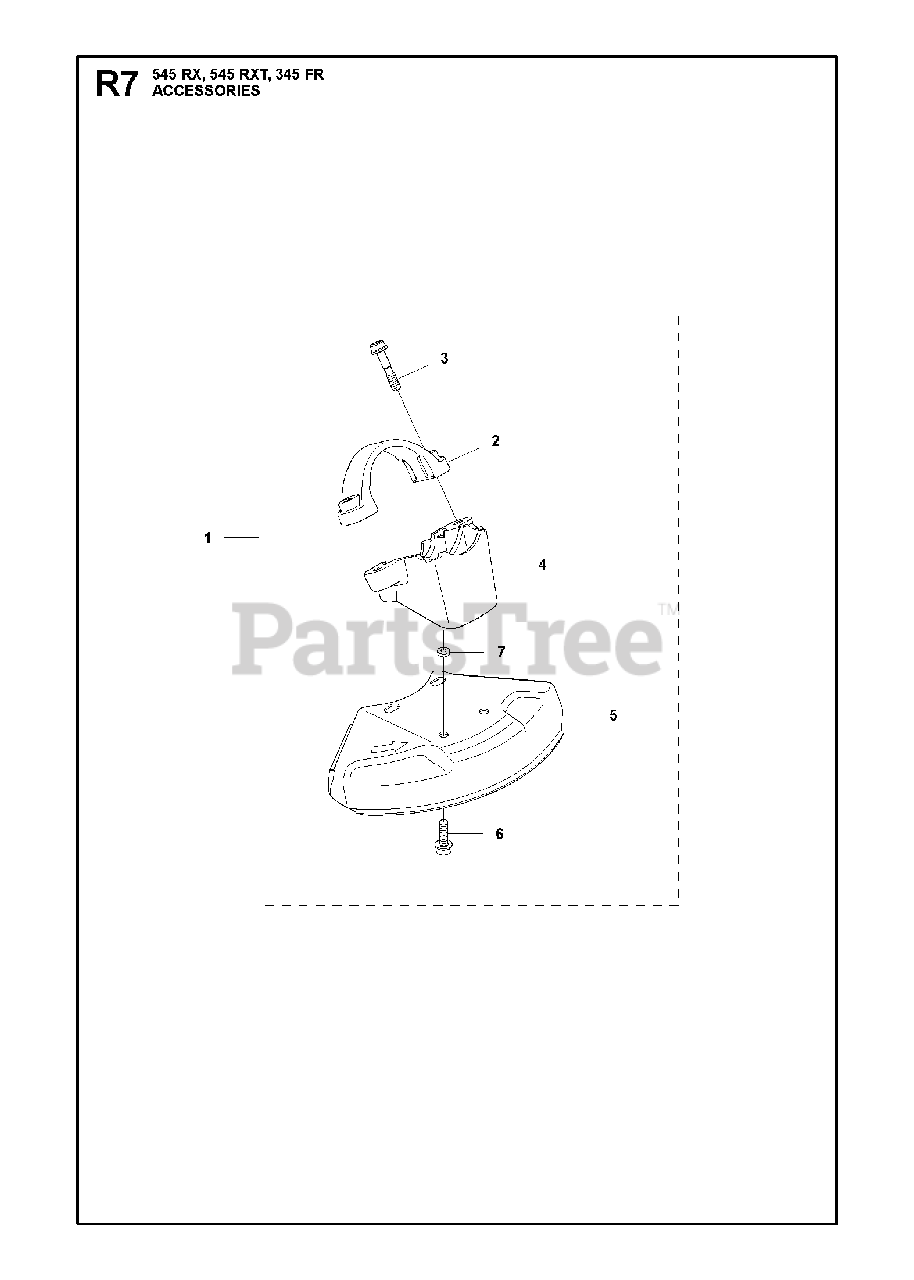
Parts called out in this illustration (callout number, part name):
1	TRIMMER GUARD ASSY
2	CLAMP
3	SCREW IHSCFMO
4	ADAPTER
5	RP BLADE GUARD
6	SCREW
7	LOCKING NUT
